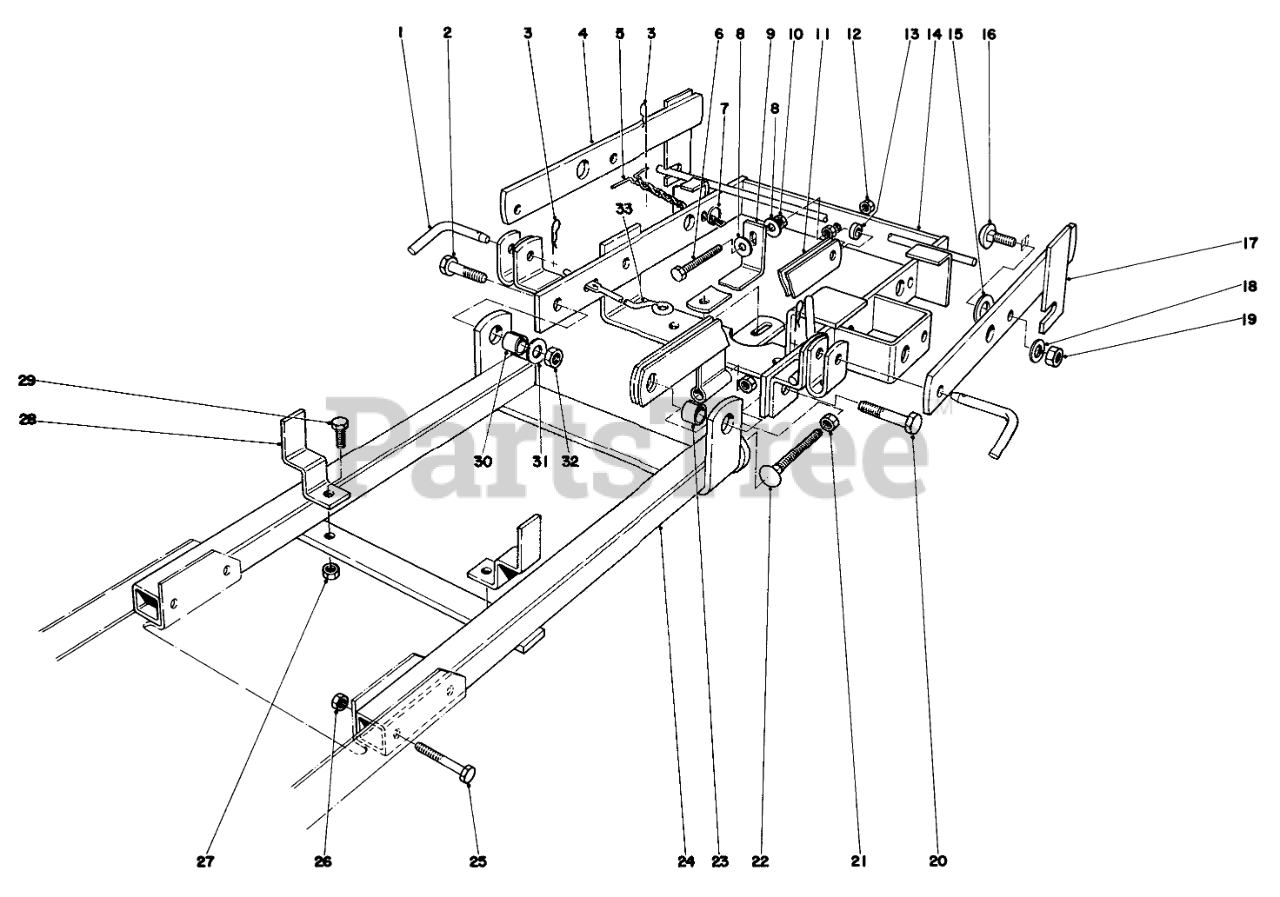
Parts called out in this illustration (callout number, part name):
1	Pin-Roller, Locating
2	SCREW-HH
3	TINNERMAN NUT
4	MountingBracket-R.H.
5	Chain & Toggle
6	SCREW-HH
7	Spring Clip
8	WASHER-FLAT
9	Bracket-Belt Adjust
10	NUT-JAM
11	Lift Extension
12	NUT-HEX
13	Spacer
14	Mounting Frame-Upper
15	Washer-Flat
16	Carriage Bolt
17	Mounting Bracket-L.H.
18	WASHER-LOCK
19	NUT-HEX
20	SCREW-HH
21	NUT-JAM
22	Carriage Bolt
23	Spacer-Bearing
24	Mounting Frame
25	SCREW-HH
26	NUT-LOCK, CONE
27	NUT-LOCK, CONE
28	Stop-Position
29	SCREW-HH
30	Spacer-Idler Pulley
31	WASHER-FLAT
32	1/2-13 CONELOCK NUT
33	Wire-Belt Guide
